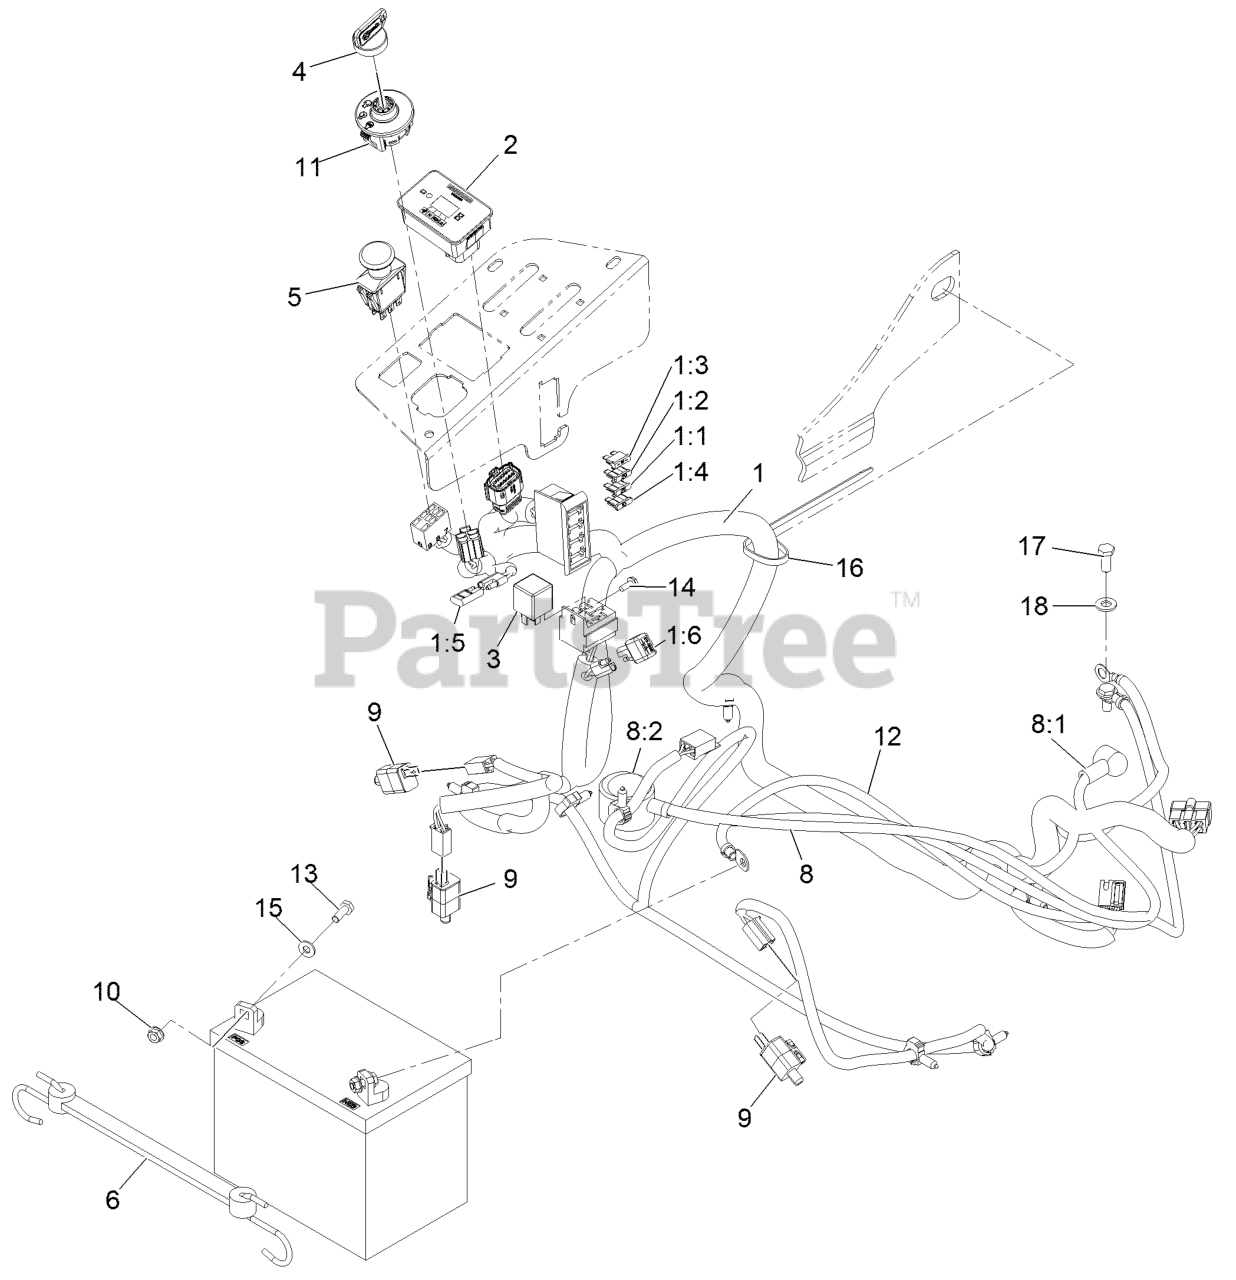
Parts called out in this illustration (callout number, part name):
1	HARNESS, WIRE
1:1	FUSE-BLADE, 25 AMP
1:2	FUSE-BLADE TYPE, 20 AMP
1:3	FUSE-BLADE, 15 AMP
1:4	FUSE-BLADE, 10 AMP
1:5	CAP-PLUG
2	MODULE ASM
4	KEYS-IGNITION (SPARE PAIR
4	KEY-IGNITION
5	SWITCH-PTO
6	HOLDDOWN-BATTERY
8	POSITIVE BATTERY CABLE AS
8:1	INSULATOR-SOLENOID
8:2	INSULATOR-BATTERY
12	CABLE-BATTERY, NEGATIVE
13	SCREW-HH
14	SCREW-TAPTITE
15	WASHER-FLAT
16	TIE-PLASTIC
17	SCREW-HH
18	WASHER-PLAIN
